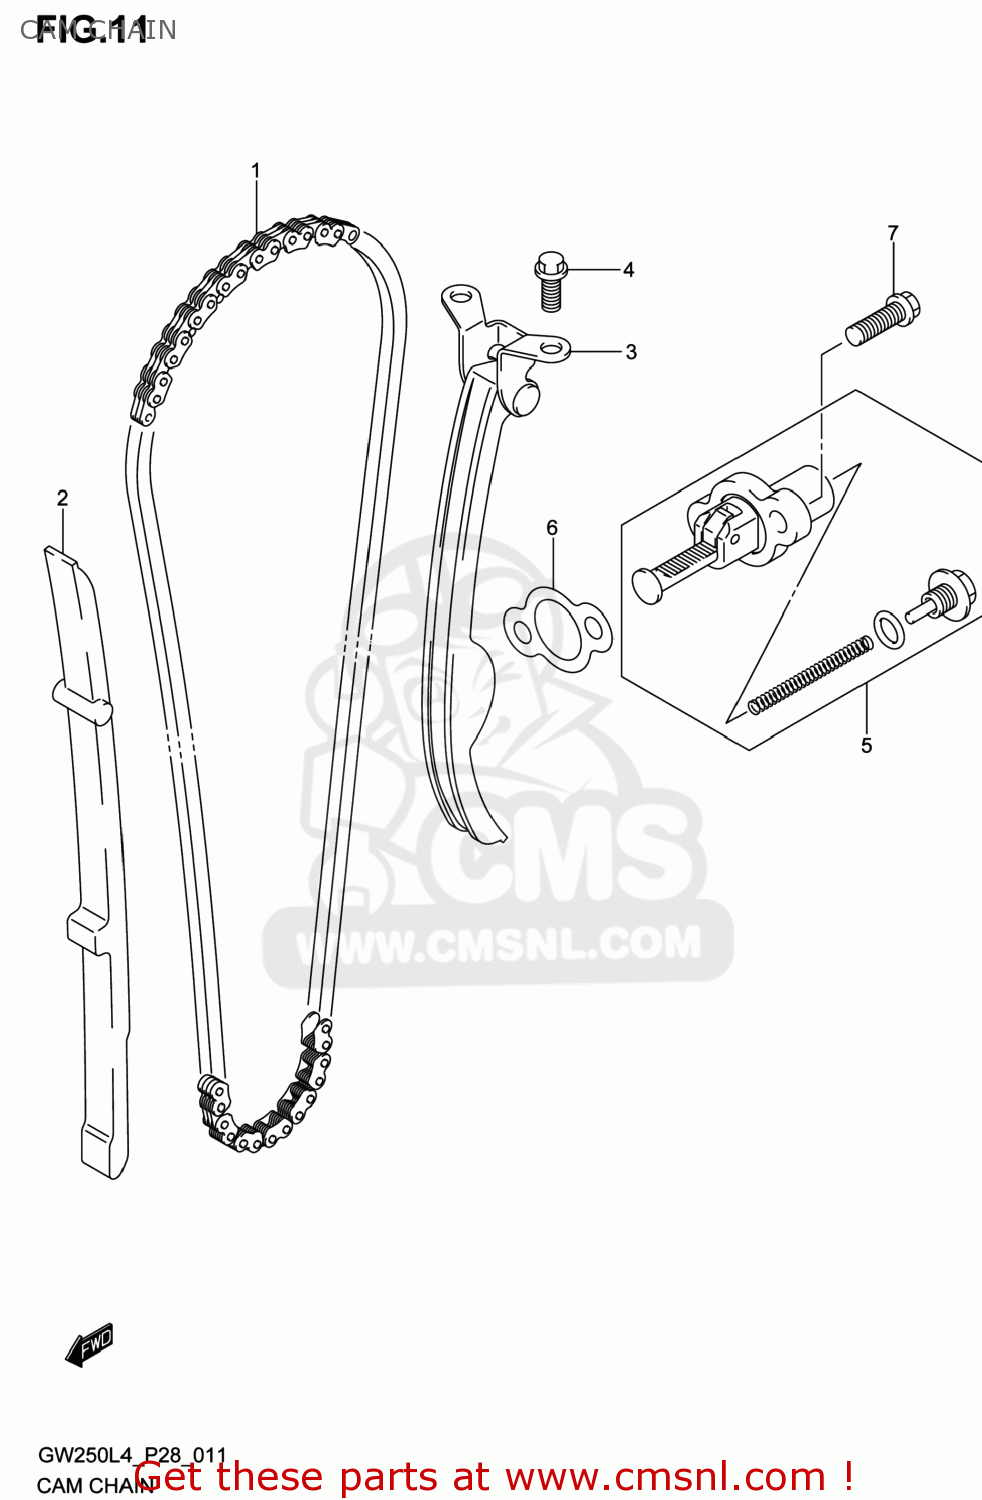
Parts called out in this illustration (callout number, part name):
1	CHAIN,CAMSHAFT DRIVE
2	GUIDE,CAM CHAIN
3	TENSIONER,CAM CHAIN
4	BOLT
5	ADJUSTER ASSY,TENSIONER
6	GASKET,TENSIONER ADJUSTER(NA) (NAS)
7	BOLT
